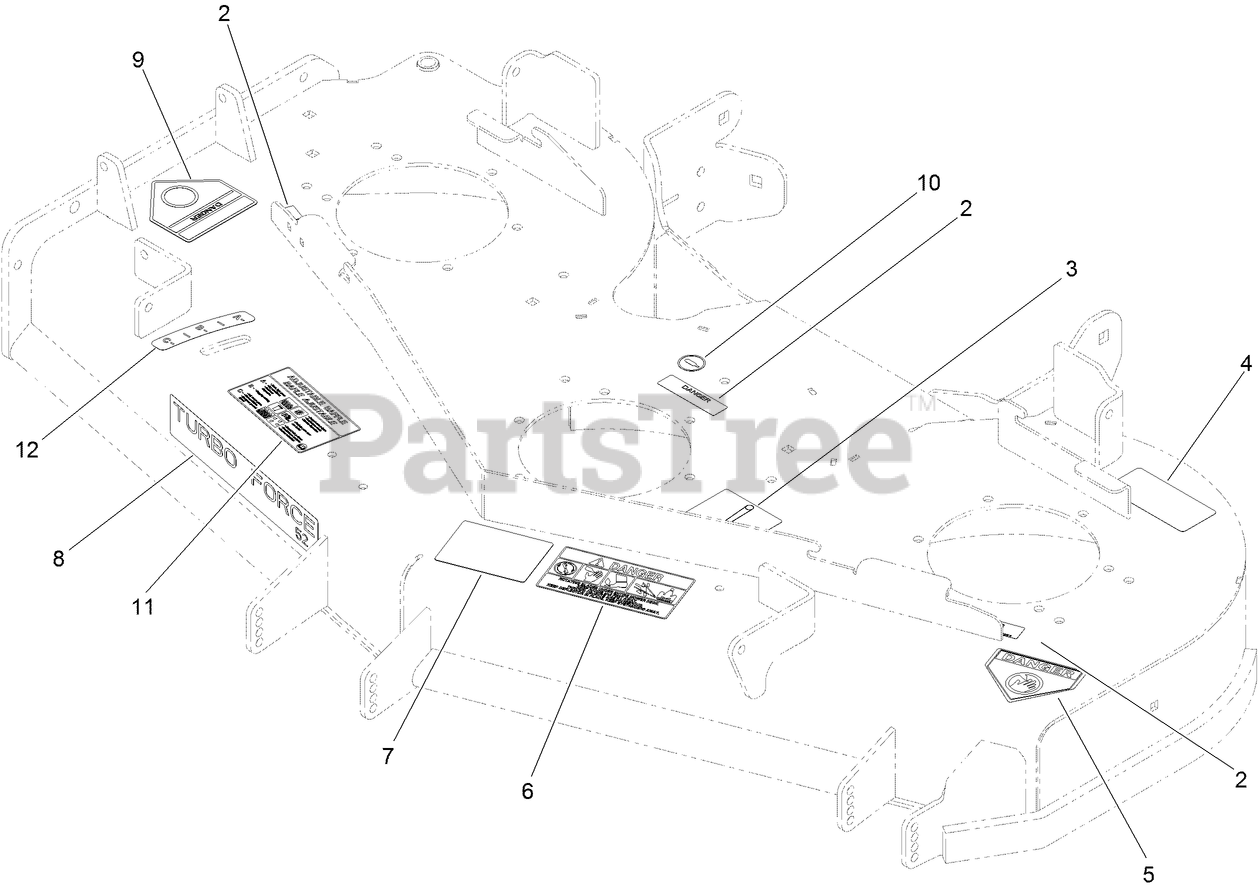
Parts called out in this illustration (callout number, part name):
2	DECAL-COVER, MISSING
3	DECAL-ROUTING, DECK BELT
4	DECAL-TORQUE
5	DECAL-DANGER
6	DECAL-DANGER, THROWN OBJECT
7	DECAL-SCALP, ANTI
9	DECAL-DANGER
10	DECAL-GREASE
11	DECAL-ADJUSTMENT, BAFFLE
12	DECAL-SETTING, BAFFLE
